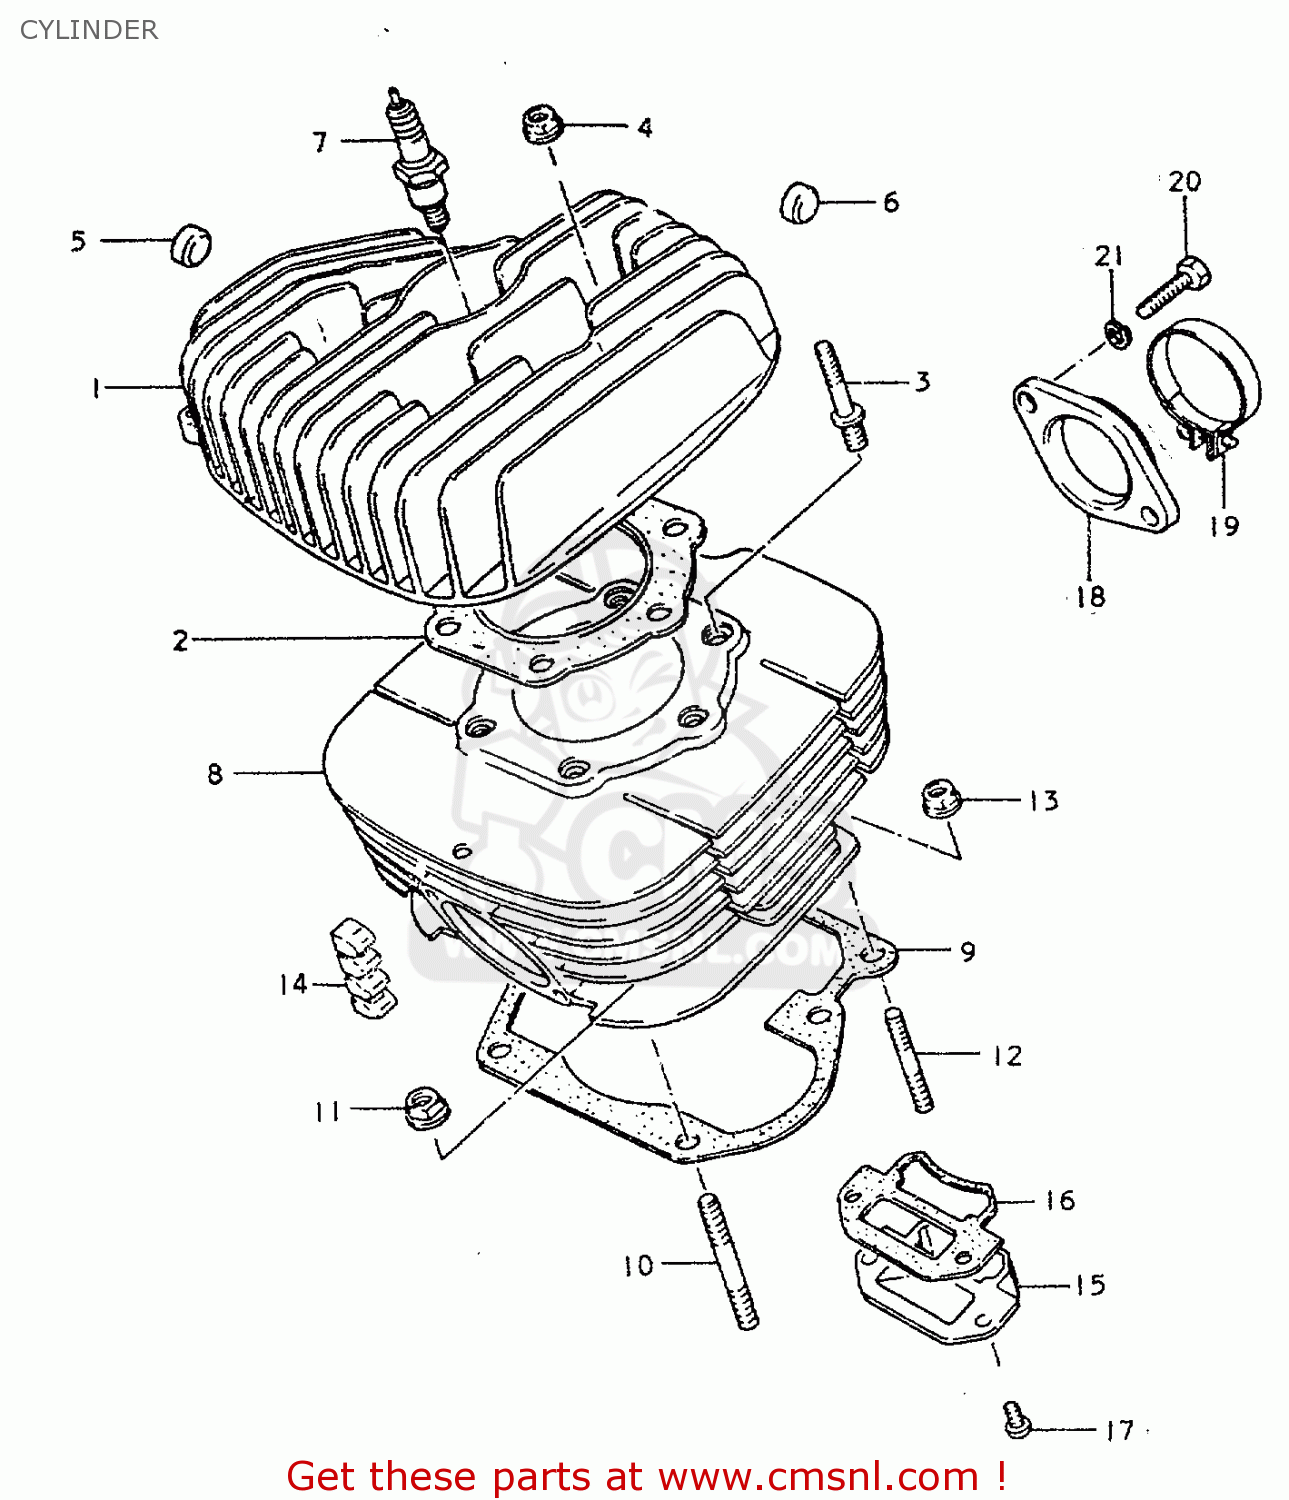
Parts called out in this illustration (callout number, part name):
1	HEAD,CYLINDER
2	GASKET,CYLINDER HEAD (NAS)
3	BOLT,STUD
4	NUT
5	PAD,CYLINDER
6	PAD,CYLINDER HEAD
7	SPARK PLUG W22EP
8	CYLINDER
9	GASKET,CYLINDER (MCA)
10	STUD 10X25
11	NUT
12	STUD 8X25
13	NUT
14	PAD,CYLINDER
15	VALVE ASSY,REED
16	GASKET,REED VALVE (MCA)
17	SCREW
18	PIPE,INTAKE
19	CLAMP
20	BOLT, UPPER
21	LOCK WASHER
